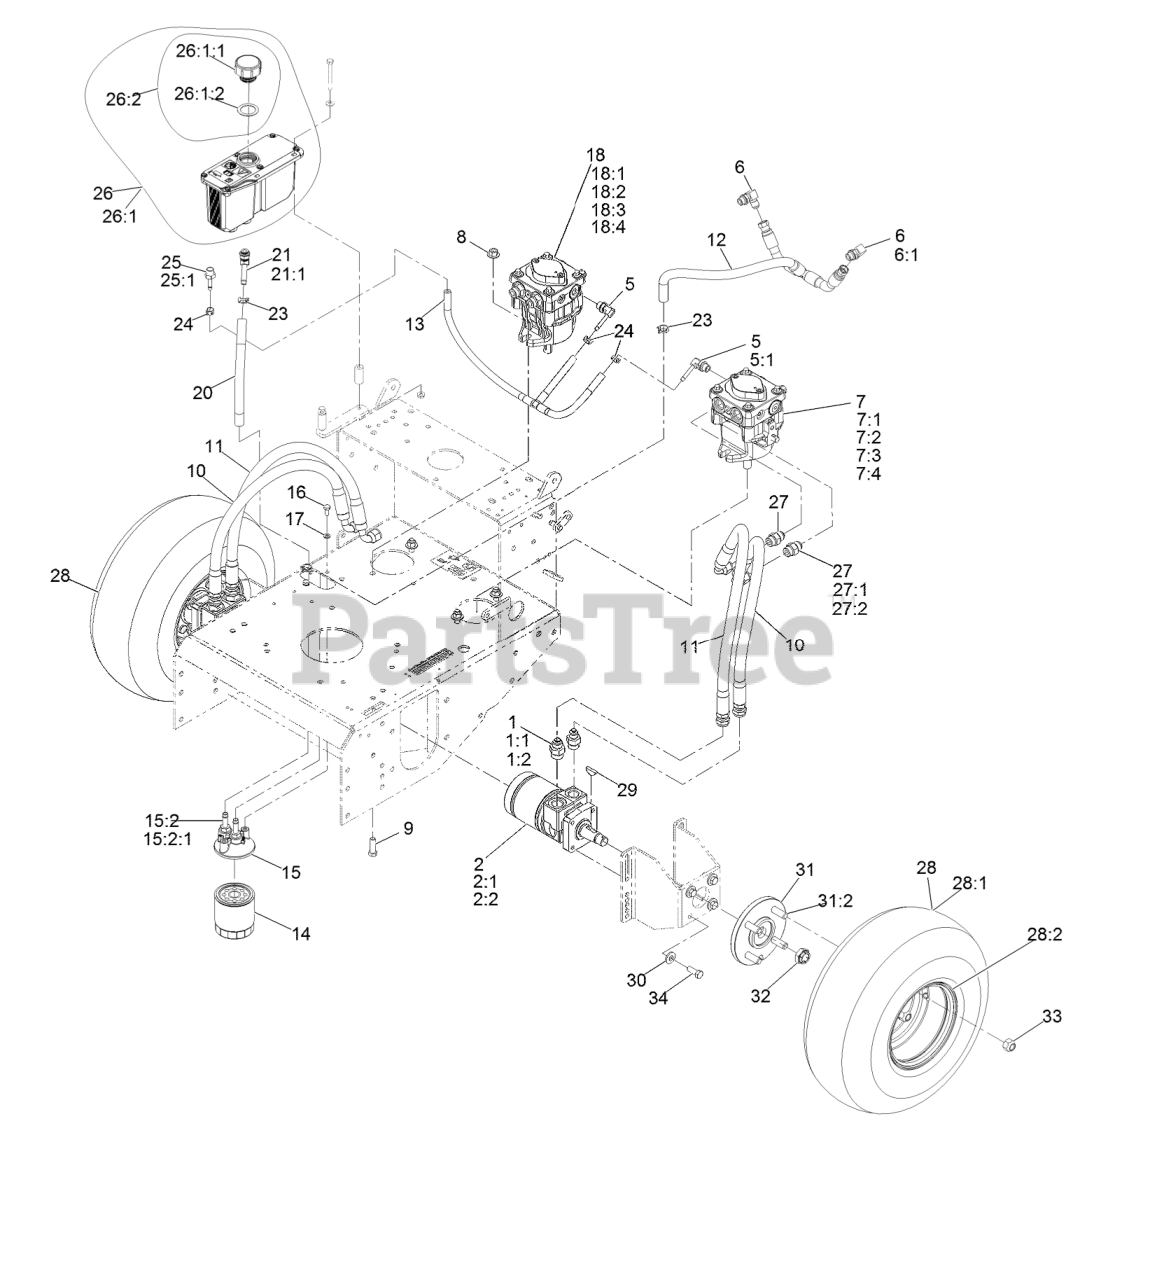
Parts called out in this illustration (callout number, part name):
1	FITTING-STRAIGHT
1:1	O-RING
2	HYD MOTOR ASM
2:1	SEAL KIT
2:2	BEARING AND SEAL KIT
5	ELBOW-90 DEG
5:1	O-RING
6	FITTING-ELBOW, 90 DEG
7	LH HYD PUMP ASM
7:1	INPUT SHAFT KIT
7:2	BEARING-THRUST
7:3	CYLINDER BLOCK KIT
7:4	SEAL OVERHAUL KIT
8	NUT-FLANGE
9	SCREW-HH
10	HYD HOSE ASM
11	HYD HOSE ASM
12	CHARGE HOSE ASM
13	CASE DRAIN HOSE ASM
14	ELEMENT-FILTER, WINTER
14	FILTER-25 MICRON, BI-DIRE
15	FILTER HEAD ASM
15:2	ADAPTER-STRAIGHT
15:2:1	O-RING
16	SCREW-HH
17	WASHER-LOCK
18	RH HYD PUMP ASM
18:1	INPUT SHAFT KIT
18:2	BEARING-THRUST
18:3	CYLINDER BLOCK KIT
18:4	SEAL OVERHAUL KIT
20	HOSE-CHARGE
21	FITTING-BARBED, 45 DEG
21:1	O-RING
23	CLAMP-HOSE
24	CLAMP-HOSE
25	ADAPTER-STRAIGHT
25:1	O-RING
26:1	Reservoir-HYD
26:1:1	Cap-Reservoir, HYD
26:1:2	GASKET-CAP
26:2	DECAL-WARNING
27	FITTING-STRAIGHT
28	WHEEL AND TIRE ASM
28:1	TIRE-TURFMASTER
28:2	RIM-WHEEL
29	KEY-WOODRUFF
30	WASHER-BELLEVILLE
31	WHEEL HUB ASM
31:2	STUD-WHEEL
32	NUT-LOCK
33	NUT-LUG
34	SCREW-HH
